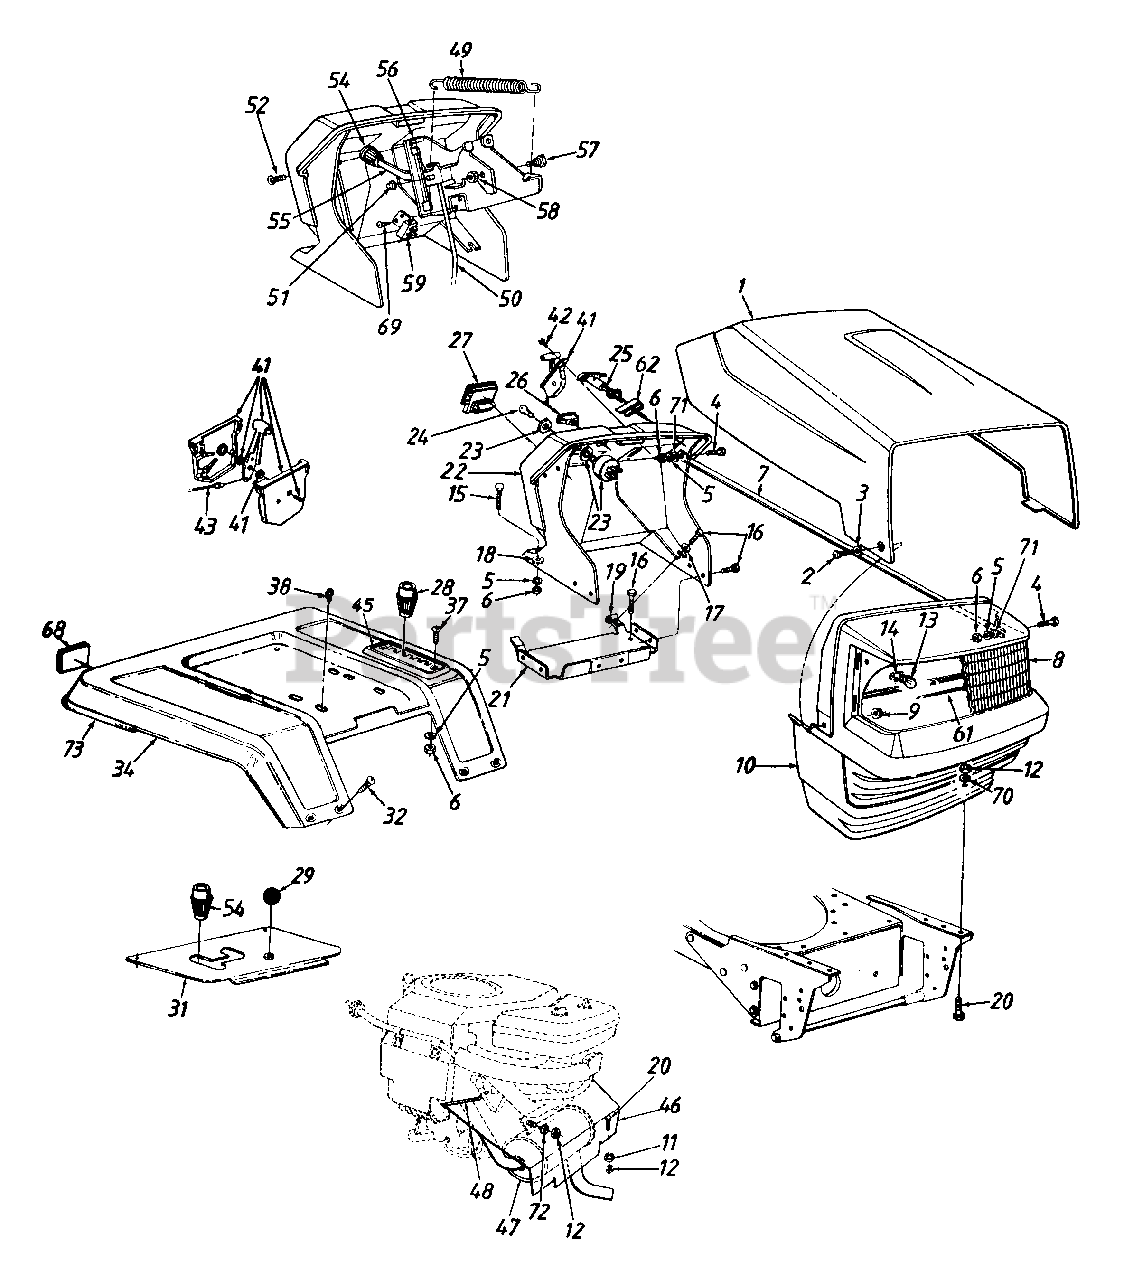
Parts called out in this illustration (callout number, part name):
3	Spr. Wash. .265" I.D. x .562" O.D.
4	Hex Bolt 1/4-20 x .62" Lg.
5	L-Wash. 1/4" I.D.
6	Hex Nut 1/4-20 Thd.
9	Flange L-Nut 1/4-28 Thd.
10	Grille
11	L-Wash. 5/16" I.D.
12	Hex Nut 5/16-18 Thd.
13	Lamp
14	Socket
15	Carriage Bolt 1/4-20 x 1.0" Lg.
16	Hex AB-Tap Scr. 1/4 x .62" Lg.
17	Fl-Wash. .281" I.D. x .73" O.D.
18	Bolt Retainer 1/4" I.D.
19	Speed Nut 1/4-20 Thd.
20	Hex Bolt 5/16-18 x .75" Lg.
23	Ignition Switch
24	Ignition Key
25	Choke Control
26	Light Switch
27	Ammeter
28	Shift Knob
31	Shift Cover
32	Carriage Bolt 1/4-20 x .5" Lg.
38	Hex Wash. Hd. AB-Tap Scr. 5/16 x .75" Lg.
41	Throttle Box Ass'y.
42	Truss Mach. AB-Tap Scr. #10 x .5" Lg.
43	Throttle Control Wire
45	6-Speed Selector Plate
46	Front Heat Shield
47	Muffler
48	Trim Strip 12" Lg.
49	Ext. Spring 5.06" Lg.
50	Deck Control Rod
51	Speed Nut 1/4" Rod
52	Torx Mach. Scr. 1/4 x .62" Lg.
54	PTO Knob
55	PTO Lever
56	PTO Bracket
57	Shld. Bolt .437" Dia. x .162"
58	Hex L-Nut 5/16-18 Thd.
59	Safety Switch (PTO)
61	Grille Reflector Label
62	Retainer Clip
68	Reflector
69	Hex Wash. Hd. B-Tap Scr. #10 x .38" Lg.
70	Fl-Wash. .344" I.D. x 1" O.D.
71	Fl-Wash. .28" I.D. x .75" O.D.
72	Spec. L-Wash. 5/16" I.D.
73	Trim Strip 81" Lg.
